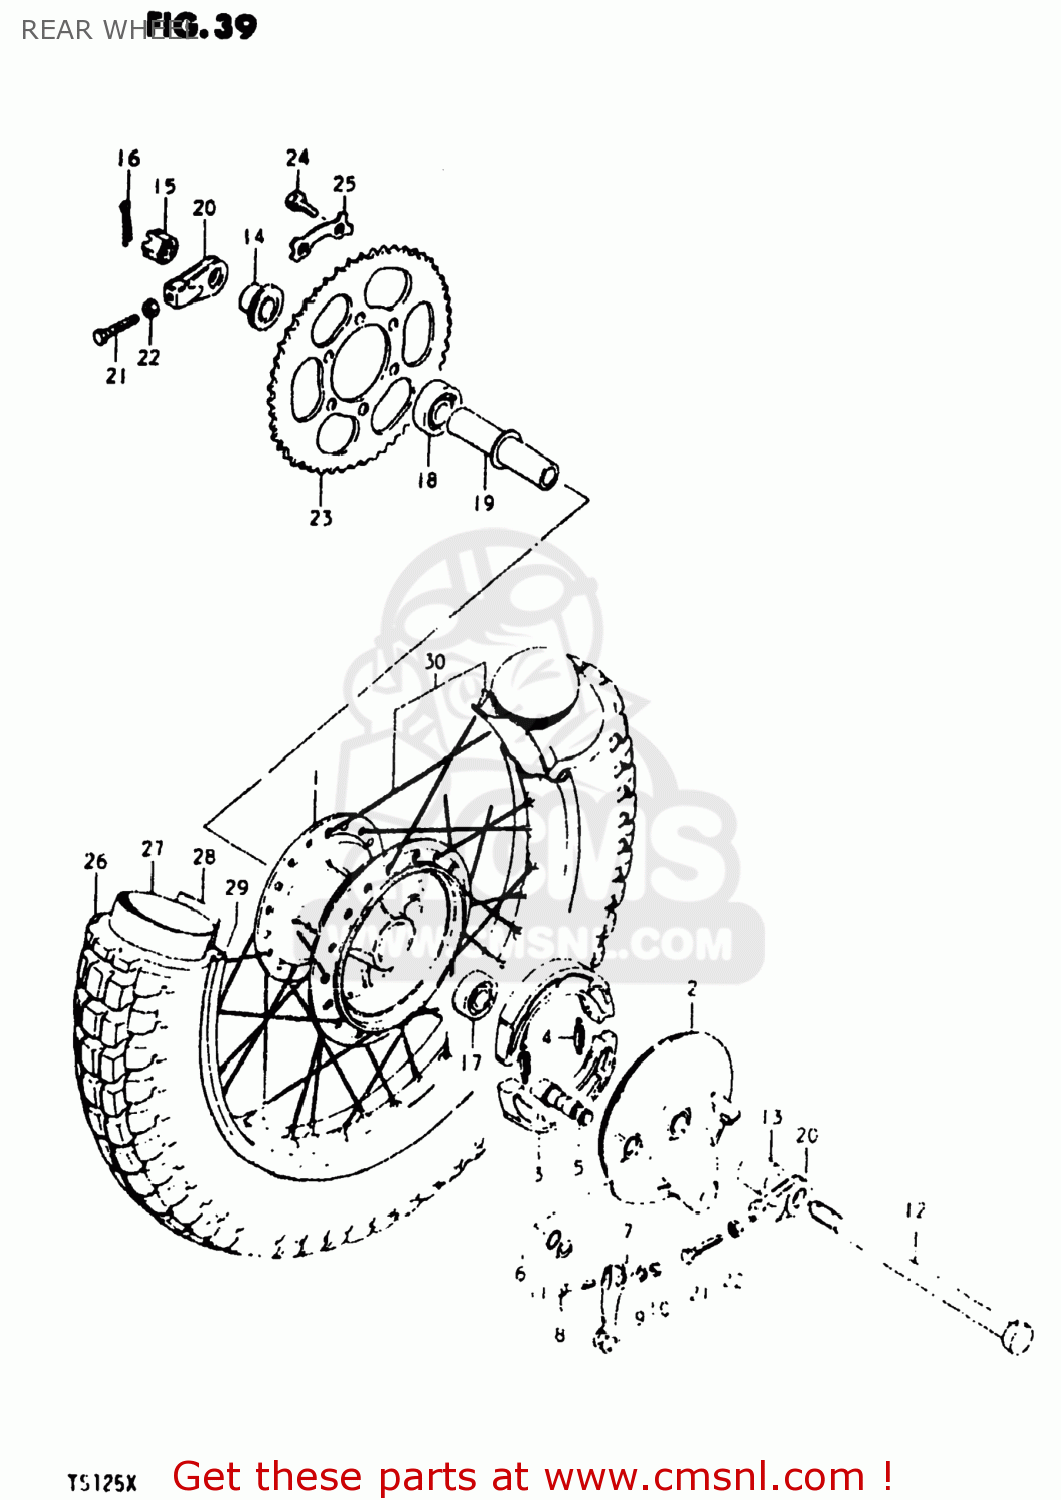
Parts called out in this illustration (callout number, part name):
1	HUB,REAR WHEEL
2	PANEL,RR BRAKE ANCHOR
3	SHOE,BRAKE
4	SPRING(L:34)
5	CAM,FRONT BRAKE
6	O-RING (D:2.4 ID:13.8)
7	LEVER,REAR BRAKE CAM
8	BOLT 6X40
9	WASHER
10	NUT
11	WASHER (14.5X22X1.6)
12	AXLE,REAR
13	SPACER(15.2X22X26)
14	SPACER,RR AXLE,L
15	NUT
16	COTTER PIN
17	BEARING
18	BEARING
19	SPACER,RR WHEEL HUB BEARING
20	ADJUSTER,CHAIN,R
21	BOLT(8X40)
22	NUT
23	SPROCKET,RR
24	BOLT(8X30)
25	WASHER
26	TIRE 4.10-18 105-458MM
27	TUBE ASSEMBLY,WHEEL,INNER
28	PROTECTOR,INNER TUBE
29	RIM,WHEEL(1.85X18)
30	SPOKE SET
